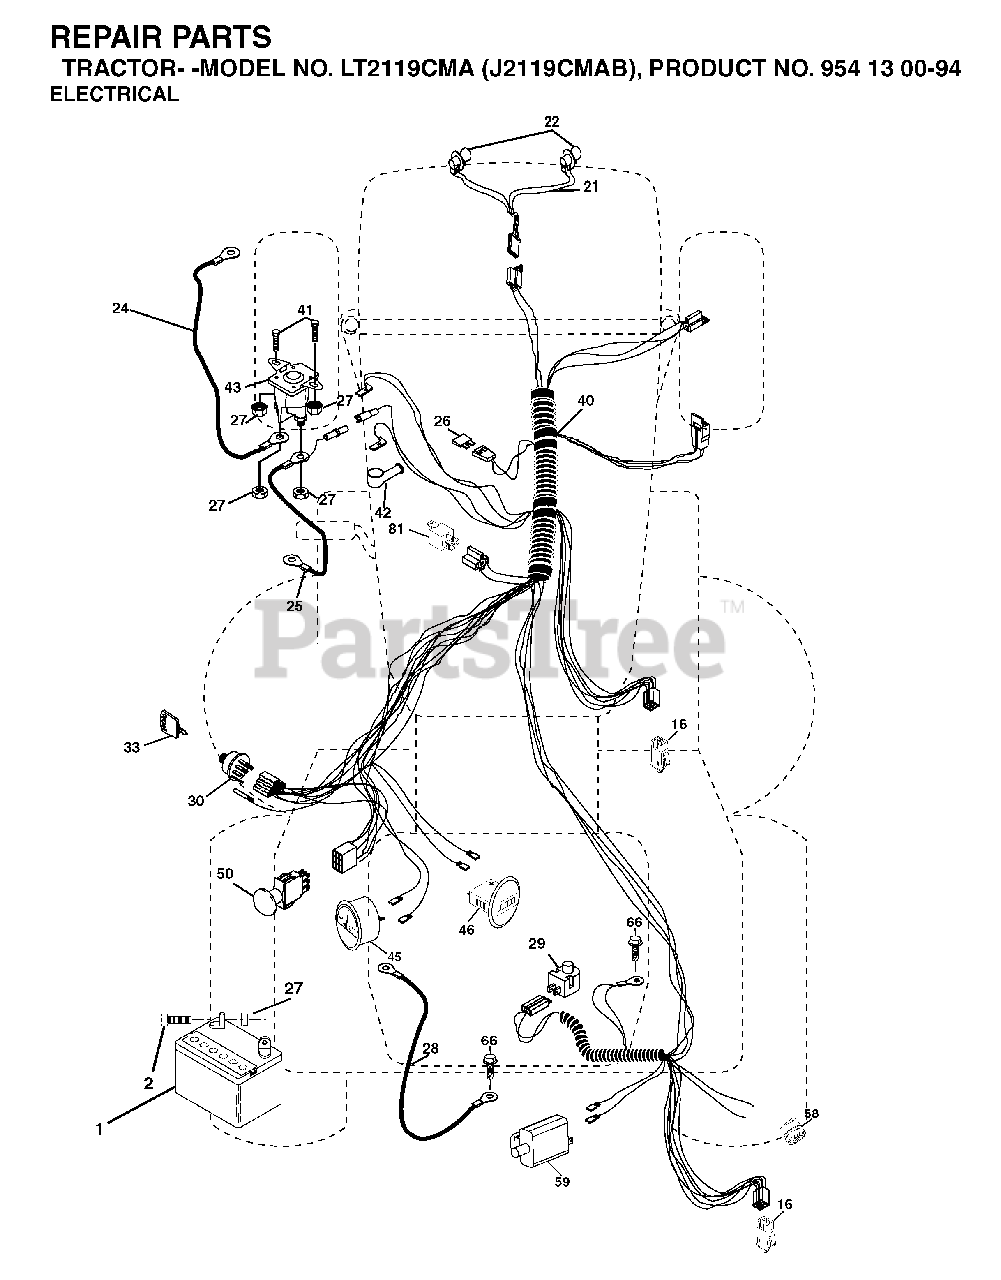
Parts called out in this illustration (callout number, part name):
1	BATTERY 12V .35 AMP
16	SWITCH INTERLOOK PUSH-IN
21	HARNESS.W/LIGHT SOCKET
22	LIGHTBULB
24	BATTERY CABLE GT
25	CABLE BATTERY
26	FUSE 20AMP
27	NUT
28	CABLE GROUND
29	PLUNGER SWITCH (COLOR:OLIVE)
30	IGNITION SWITCH
33	KEY MLD GEN DELTA
42	TERMINAL COVER
43	SOLENOID
46	HOURMETER SNAP-IN
50	PTO SWITCH
58	BUZZER
79	BULB HOLDER ASM.
81	RELAY.ASSY.T
